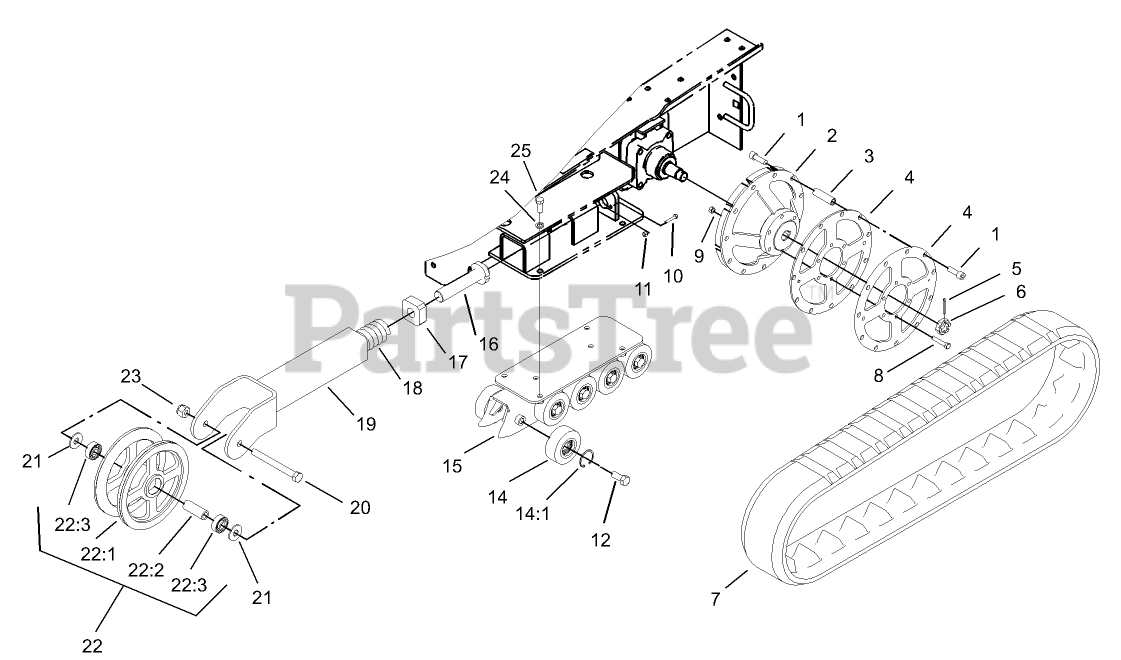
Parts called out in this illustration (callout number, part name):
1	SCREW-HSH
2	Drive Wheel ASM
3	SPACER-WHEEL, DRIVE
4	PLATE-WHEEL, DRIVE
5	PIN-COTTER
7	TRACK
8	SCREW-HH
9	NUT-LOCK, SIDE
10	SCREW-HH
11	NUT-LOCK, NI
12	SCREW-HH
14	BOGGY WHEEL ASM
14:1	RING-RETAINING
15	TRACK GUIDE ASM
16	BOLT-TENSIONER
17	BLOCK-TENSIONER
18	SPRING-COMPRESSION
19	TENSIONER ARM ASM
20	SCREW-HH
21	WASHER-FLAT
22	TENSIONER WHEEL ASM
22:1	WHEEL-TENSIONER
22:2	SPACER-WHEEL, TENSIONER
22:3	BEARING
23	NUT-HEX
24	WASHER-LOCK
25	SCREW-HH
